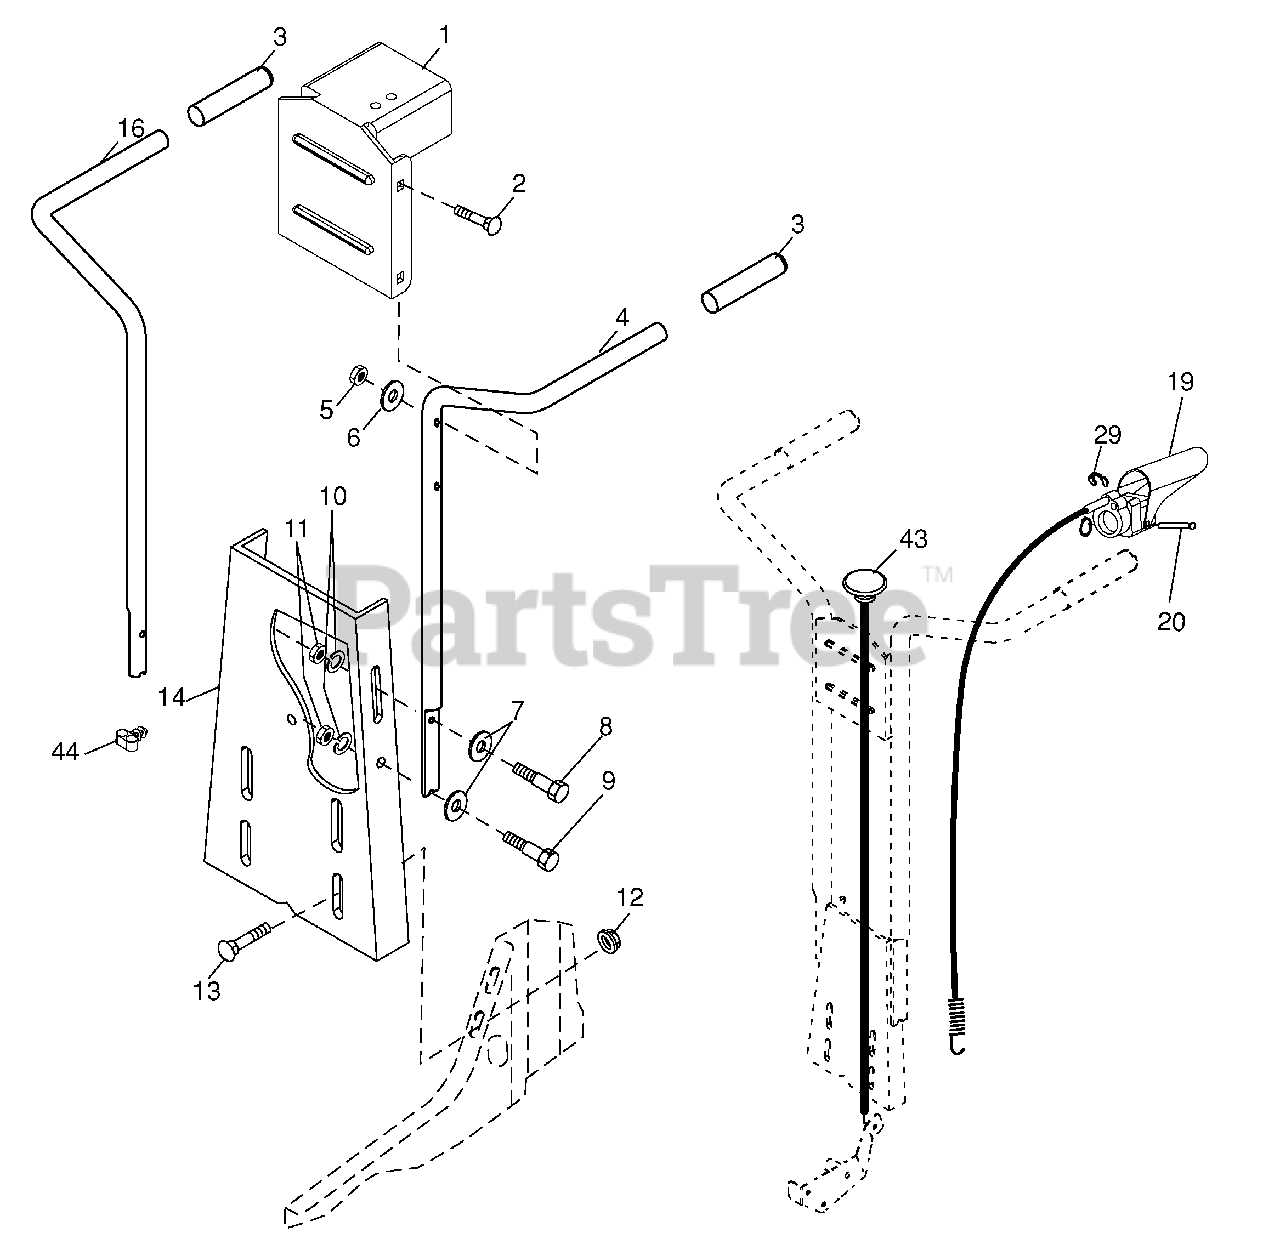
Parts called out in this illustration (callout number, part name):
1	Bracket, Handle
2	Bolt, Carriage 5/16-18 x 1-1/2
3	Grip, Handle
4	Handle, L.H.
5	Nut, Hex, Crownlock 5/16-18
6	Washer 11/32 x 11/16 x 16 Gauge
7	Washer 3/8 x 7/8 x 14 Gauge
8	Bolt, Hex Head 5/16-18 x 1-1/4
9	Bolt, Hex Head 5/16-18 x 1
10	Washer, Lock 5/16
11	Nut, Hex 5/16-18
12	Nut, Hex, Flanged 5/16-18
13	Bolt, Carriage, Gr. 5 5/16-18 x 3/4
14	Panel, Handle
16	Handle, R.H.
19	Tine Control Lever Assembly
20	Pin, Pivot
29	Retaining Ring
43	Cable Assembly, Reverse
44	Clip
